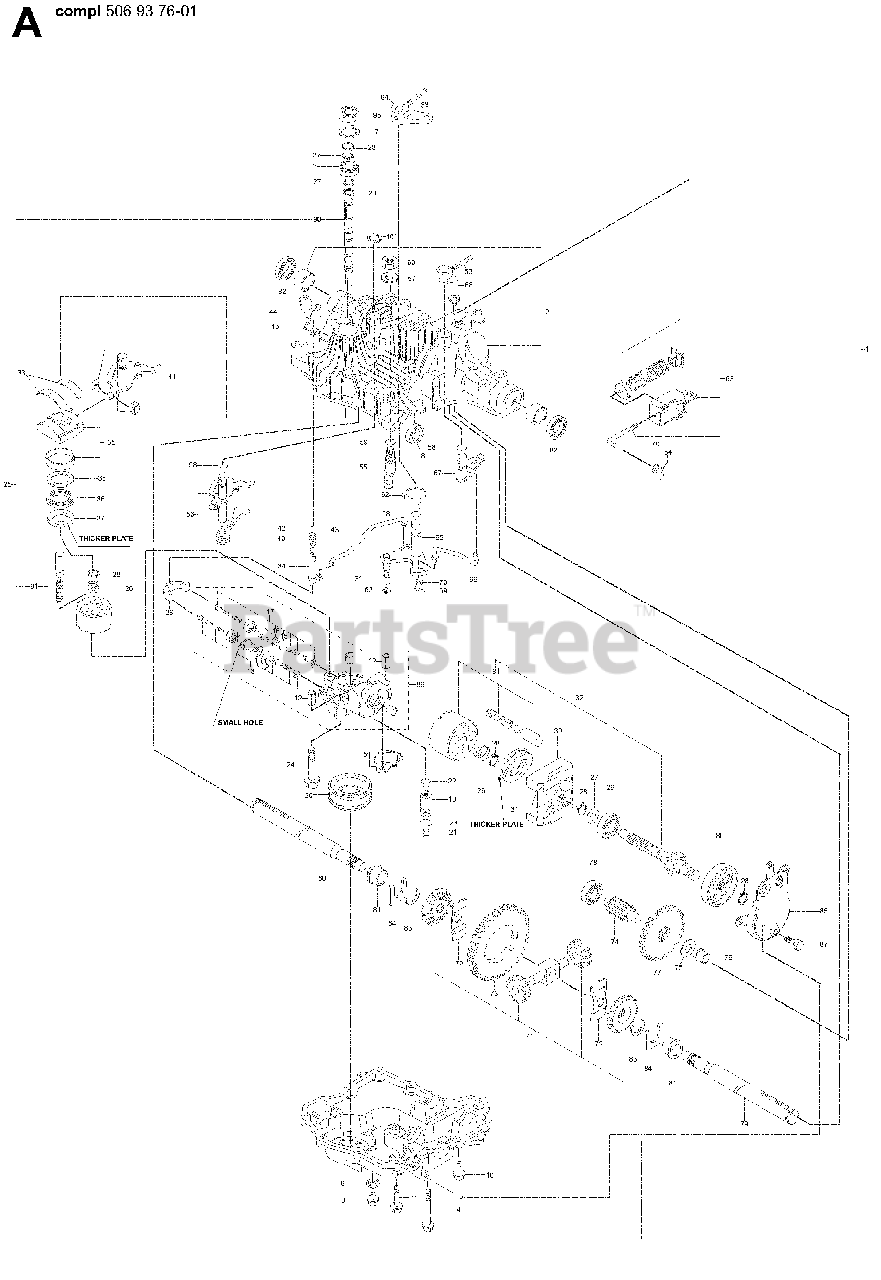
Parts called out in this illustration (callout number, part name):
1	K61 HSQ-EU
2	UPPER CASE KIT
3	LOWER CASE K61
4	"SCREW, CAP 8 75"
5	MAGNET CASE K60
10	TAPPING SCREW
20	FILTER K61
25	PUMP SHAFT
26	PUMP SPRING
27	WASHER 15x20x1
28	SNAP RING S15
30	"HOUSING K61,K65"
31	"BEARING, THURST"
32	MOTOR SHAFT 15
33	METAL THRUST
34	BYPASS SHAFT
35	SWASH PLATE COMP
36	THRUST BEARING K81106
37	THRUST PLATE A
38	THRUST PLATE B
43	BYPASS ROD
44	ARM VALVE RELEASE
54	PIN 2.0 X 20
55	FULCRUM 10
62	RETURN BRAKE SPRING
65	BRAKE SHAFT
67	BRAKE ARM A
68	BRAKE ARM B
71	DIFFERENTIAL GEAR KIT
72	THRUST WASHER
73	FINAL GEAR 55
74	FINAL PINION SHAFT
76	BUSHING 15
77	FINAL GEAR SHAFT 41
78	BEARING 6203
79	AXLE SHAFT LEFT (H.L.#840)
80	AXLE SHAFT RIGHT (H.L.#839)
81	BUSHING 22
82	SEAL (S 25.4x42x8)
84	THRUST WASHER
85	BRAKE BAND
86	BRAKE DRUM
87	BOLT W/WASHEER 8x20
89	CENTER CASE KIT
102	INPUT SHEAVE
